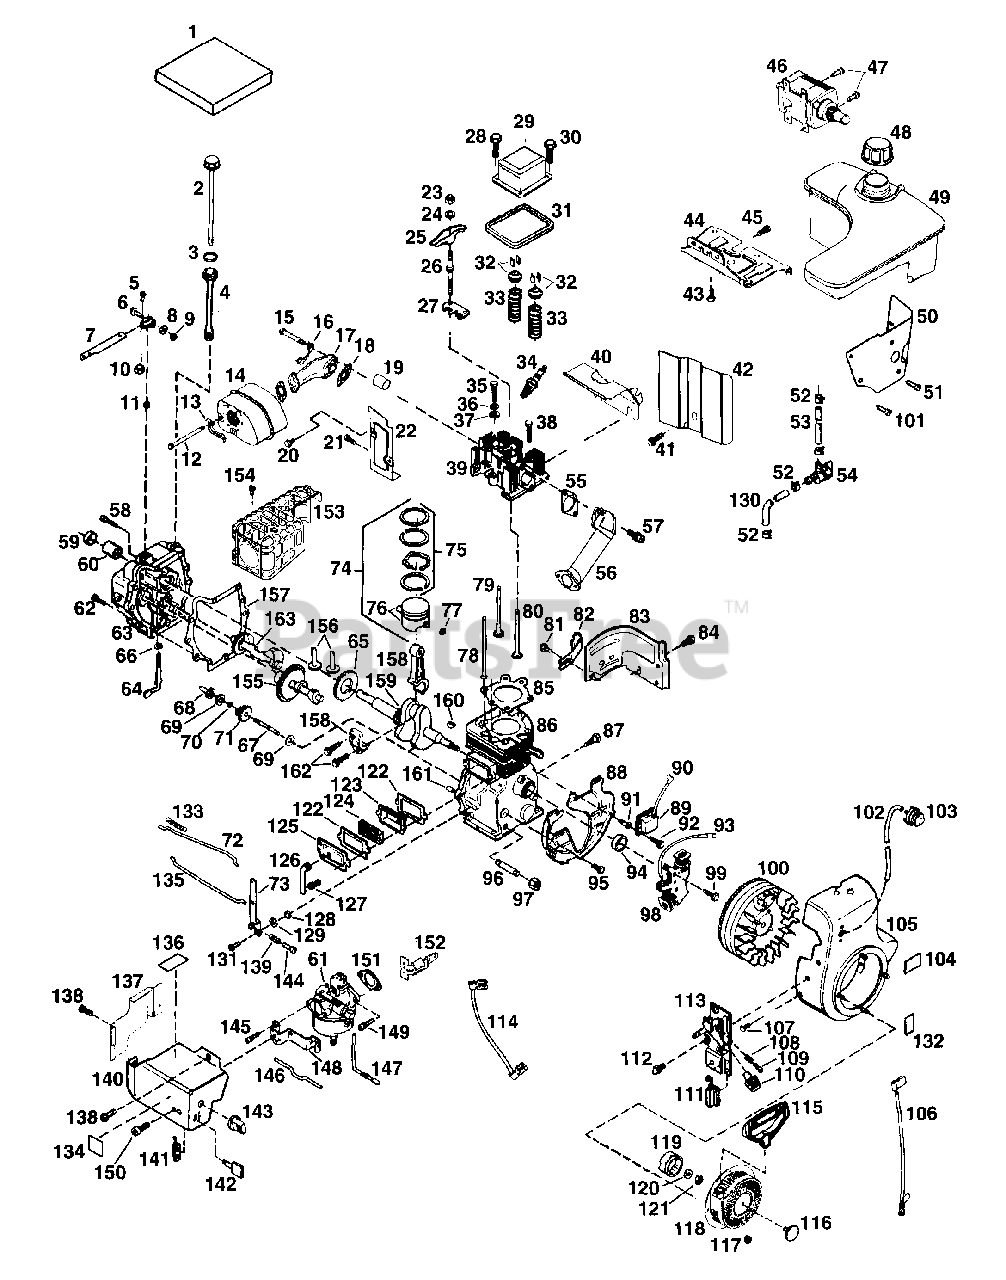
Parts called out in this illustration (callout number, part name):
1	Gasket Set
4	Oil Fill Tube
5	Screw, Torx T-15, 8-32 x 3/8"
6	Screw, 10-32 x 3/4"
7	Governor Lever
8	Lock Washer
9	Lock Nut, 10-32
10	Lock Nut, 10-32
11	Retaining Ring
12	Screw, 5/16-18 x 4-1/2"
13	Locking Plate
15	Screw, 5/16-18 x 1-9/32"
16	Locking Plate
17	Exhaust Manifold
18	Exhaust Gasket
19	Exhaust Port Liner
20	Screw, Torx T-30, 1/4-20 x 1/2"
21	Lock Nut, 10-32
22	Blower Housing Extension
24	Lock Washer
25	Rocker Arm
26	Rocker Arm Stud
27	Push Rod Guide
28	Valve Cover Mounting Stud
29	Rocker Arm Cover
30	Screw, Torx T-30, 1/4-20 x 1/2"
31	Rocker Arm Cover Gasket
32	Valve Spring Keeper
33	Valve Spring
34	Spark Plug (RN4C)
35	Screw, 5/16-18 x 2-1/2"
36	Belleville Washer
38	Screw, Torx T-30, 1/4-20 x 15/32"
39	Cylinder Head
40	Cylinder Head Cover
41	Screw, 10-32 x 1/2"
42	Heat Baffle
43	Screw, 1/4-15 x 3/4"
44	Fuel Tank Bracket
45	Screw, 5/16-18 x 7/8"
46	Electric Starter Motor (110 Volt)
47	Screw, Torx T-30, 1/4-20 x 15/32"
48	Fuel Cap
49	Fuel Tank
50	Fuel Tank Extension
51	Screw, 10-32 x 1/2"
52	Fuel Line Clamp
53	Fuel Line
54	Fuel Shut-Off Valve
55	Intake Pipe Gasket
56	Intake Pipe
57	Screw, Torx T-30, 5/16-18 x 7/8"
58	Screw, 1/4-20 x 1-3/16"
60	Crankshaft Bushing
61	Carburetor
62	Screw, 1/4-20 x 1-11/16"
63	Cylinder Cover
64	Governor Rod
65	Counterbalance Gear
66	Governor Yoke
67	Governor Shaft
68	Governor Spool
70	Retaining Ring
71	Governor Gear Ass'y
72	Governor Link
73	R.P.M. Adjusting Lever
74	Piston, Pin & Ring Set (Std.)
75	Ring Set (Std.)
76	Piston & Pin Ass'y (Std.)
77	Piston Pin Retaining Ring
79	Exhaust Valve (Std.)
80	Intake Valve (Std.)
81	Screw, 10-24 x 3/16"
82	Fill Tube Clip
83	Blower Housing Extension
84	Screw, Torx T-30, 1 /4-20 x 1/2"
85	Cylinder Head Gasket
86	Cylinder
87	Screw, 1/4-20 x 1/2"
88	Blower Housing Baffle
89	Solid State Ignition
90	Spark Plug Cover
91	Solid State Mounting Stud
92	Screw, Torx T-15, 10-24 x 15/16"
95	Screw, 1/4-20 x 5/8"
96	Oil Drain Extension
97	Extension Cap
98	Alternator Coil (18 Watt)
99	Screw, 1/4-20 x 3/4"
100	Flywheel (W/Ring Gear)
101	Screw, 12-16 x 5/8"
102	Primer Line
103	Primer Ass'y
104	Primer Decal
105	Blower Housing
106	Ground Wire
107	Screw, Torx T-40, 5/16-24 x 21/32"
108	Compression Spring
109	Screw, Torx T-10, 5-40 x 7/16"
110	Control Knob
112	Screw, 10-32 x 1/2"
113	Control Bracket
114	Ground Wire
115	Starter Handle
116	Starter Decal
117	Nut & Lock Washer, 1/4-28
118	Rewind Starter
119	Cylinder Head Gasket
120	Lock Washer
121	Flywheel Nut
122	Valve Cover Gasket
123	Breather Body
124	Breather Element
125	Valve Cover
126	Breather Tube
127	Screw, 10-24 x 1/2"
130	Fuel Line
131	Screw, 10-32 x 5/8"
132	Instruction Decal
133	Extension Spring
134	Caution Decal
135	Throttle Link
136	Warning Decal
137	Carburetor Cover
138	Screw, 10-32 x 1/2"
139	Compression Spring
140	Carburetor Cover (Front)
142	Key Switch
143	Choke Knob
144	Screw, Torx T-10, 6-32 x 41/64"
145	Screw, 10-32 x 1/2"
146	Choke Spring
147	Choke Rod
148	Choke Bracket
149	Screw, 1/4-20 x 27/32"
150	Screw, 10-32 x 1/2"
151	Carburetor To Intake Pipe Gasket
152	Key Switch Bracket
153	Heat Shield
154	Screw, 10-32 x 5/16"
155	Camshaft (MCR)
156	Valve Lifter
157	Cylinder Cover Gasket
158	Connecting Rod Ass'y
159	Crankshaft
160	Flywheel Key
161	Dowel Pin
162	Connecting Rod Bolt
163	Counterbalance Weight
